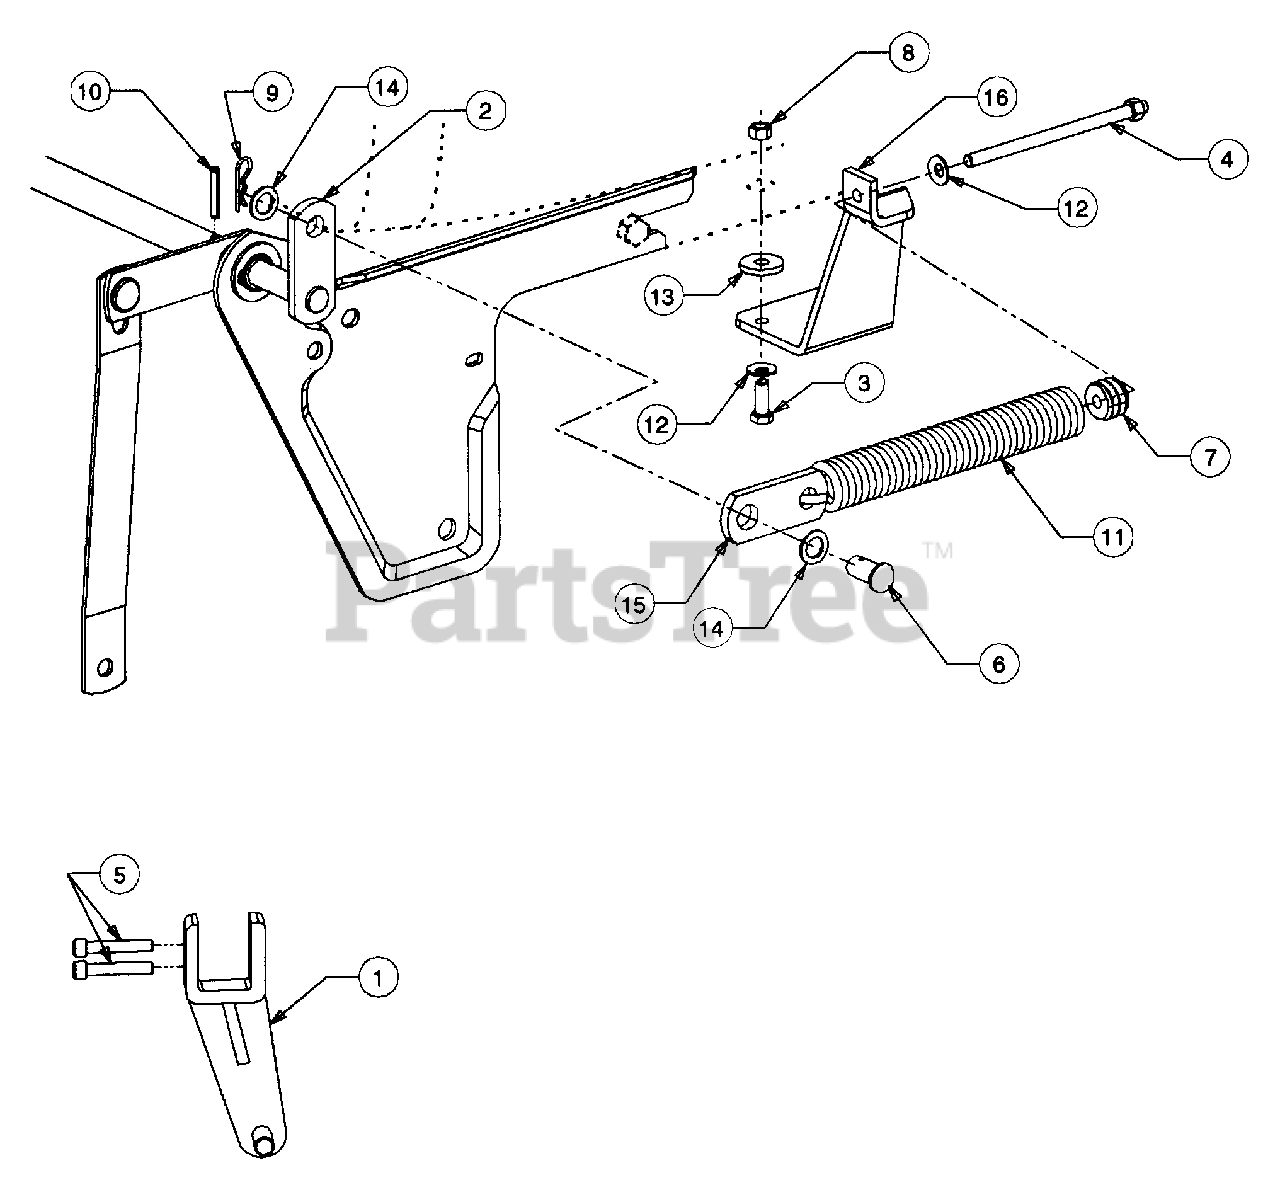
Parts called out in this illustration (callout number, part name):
1	Bracket Ass'y, Manual Lift
4	Screw, Hex Special
5	Screw, Socket Head
6	Pin, Clevis, .62 Dia X 1.20 Lg
7	Insert, Spring
8	Nut, Hex, 3/8-16
9	Pin, Internal Cotter
10	Pin, Spiral Spring, .250 Dia X 1.5 Lg
11	Spring, Extension
12	Washer, Bell
13	Washer, Flat, .406 X 1.25 X .172
14	Washer, Flat, .635 X 1.00 X .063
